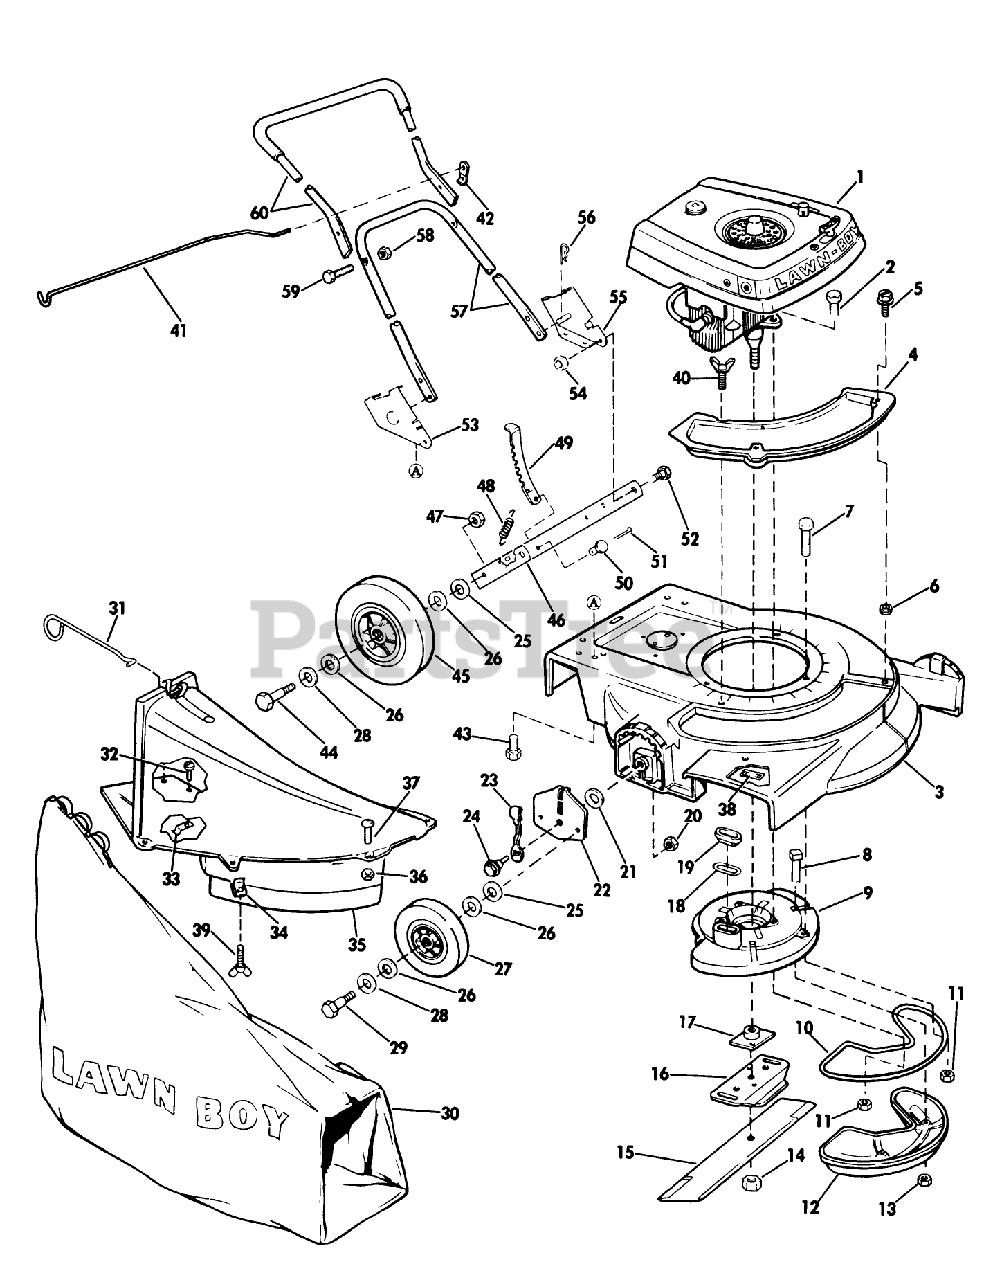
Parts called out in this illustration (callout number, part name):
5	SCREW SEMS TRM HEX HD
13	LOCKNUT E
14	NUT-BLADE
17	PLATE AND COLLAR ASM
18	GASKET S
25	WASHER WROUGHT
29	BOLT WHEEL
30	89802 LB WHOLE GOODS
34	SPEED NUT ARDEN
35	Skirt Assembly
41	ROD & CLIP
47	LOCKNUT
48	SPRING N.A.S
52	BOLT-SHOULDER
56	HAIR PIN
